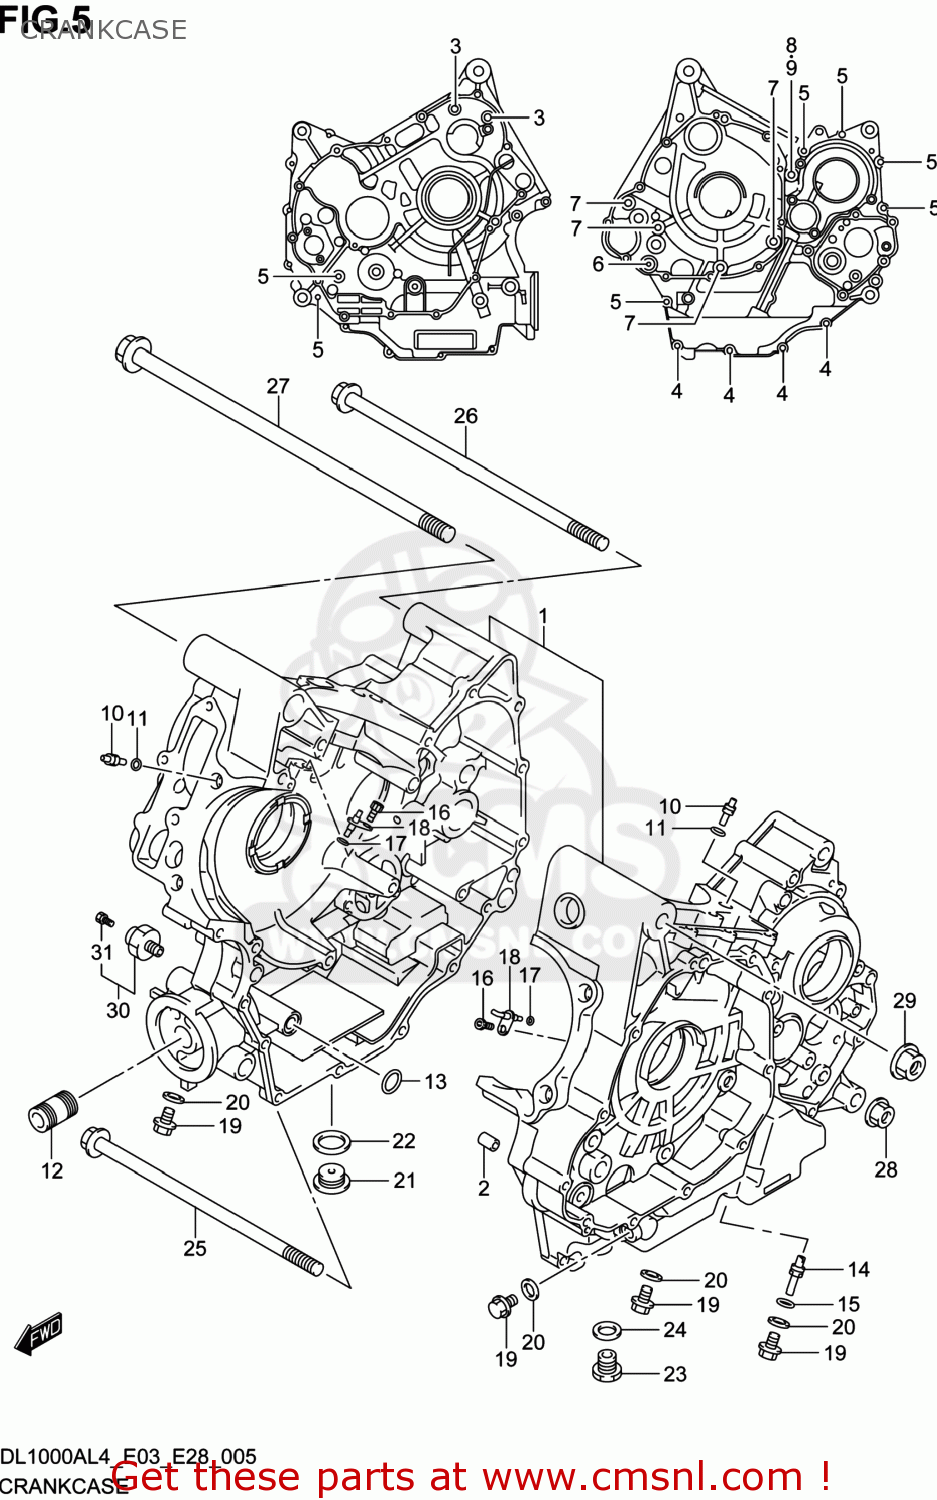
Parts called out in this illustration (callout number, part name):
1	CRANKCASE SET
2	PIN,CRANKCASE
3	BOLT(8X110)
4	BOLT
5	BOLT
6	BOLT
7	BOLT
8	BOLT(8X125)
9	WASHER
10	JET,AIR(14)
11	O RING(D:1.2,ID:4)
12	UNION,OIL STAND
13	O RING(D:1.9,ID:12.6)
14	JET,OIL GALLERY
15	O RING(D:1.2,ID:4)
16	BOLT(6X12)
17	O RING(D:1.2,ID:4.7)
18	JET,PISTON COOLING
19	BOLT
20	GASKET(8.2X14X1) (NAS)
21	PLUG,16X8
22	GASKET(16X22X2) (NAS)
23	PLUG(14X20)
24	GASKET(13.8X18.8X4.8) (NAS)
25	BOLT(10X225)
26	BOLT(10X265)
27	BOLT(12X300)
28	NUT
29	NUT
30	SWITCH ASSY,OIL PRESSURE
31	BOLT,OIL PRESSURE SWITCH
